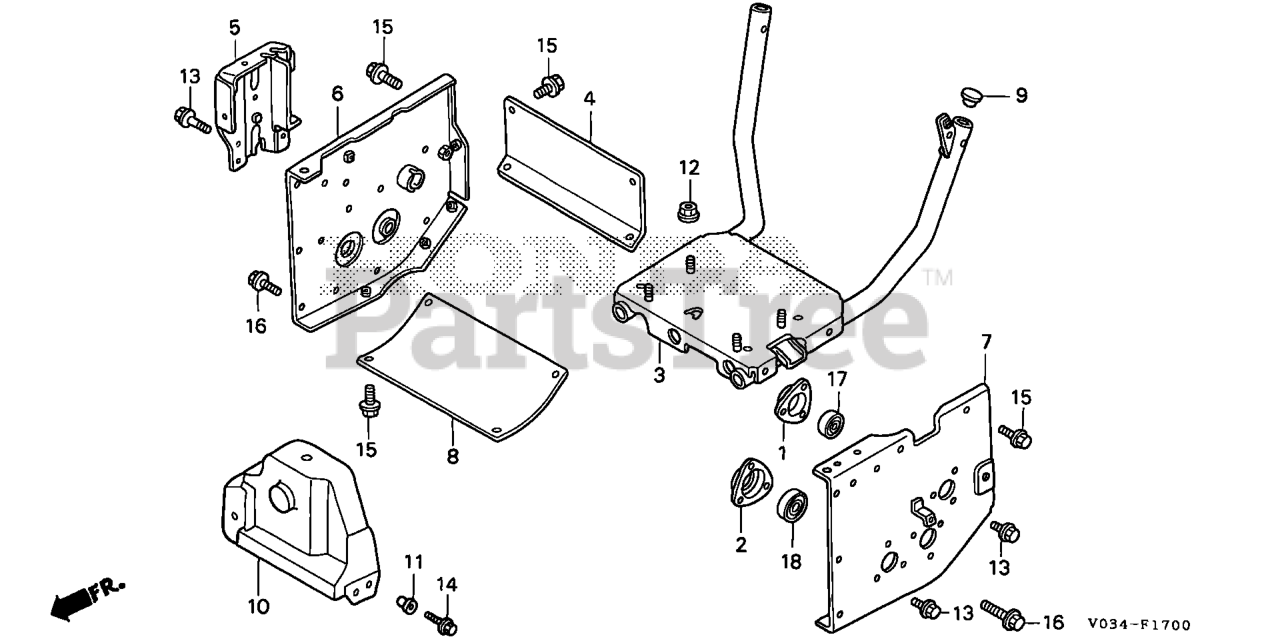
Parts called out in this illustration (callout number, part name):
1	HOLDER, BEARING
2	HOLDER, WHEEL SHAFT BEARING
3	BED, ENGINE
4	STAY, ENGINE BED
5	HOLDER, WIRE
6	STAY, R. ENGINE BED
7	STAY, L. ENGINE BED
8	STAY, ENGINE BED (B)
9	CAP, HANDLE (LOWER)
10	COVER, BELT
11	WASHER, CHAIN CASE SETTING
12	NUT, FLANGE (10MM)
13	BOLT, FLANGE (6X12) Use up to Engine SN 1543277.
14	BOLT, FLANGE (6X14)
15	BOLT, FLANGE (8X12)
16	BOLT, FLANGE (8X16) Use from Engine SN 1000016.
17	BEARING, RADIAL BALL (6004UU)
18	BEARING, RADIAL BALL (6201UU)
